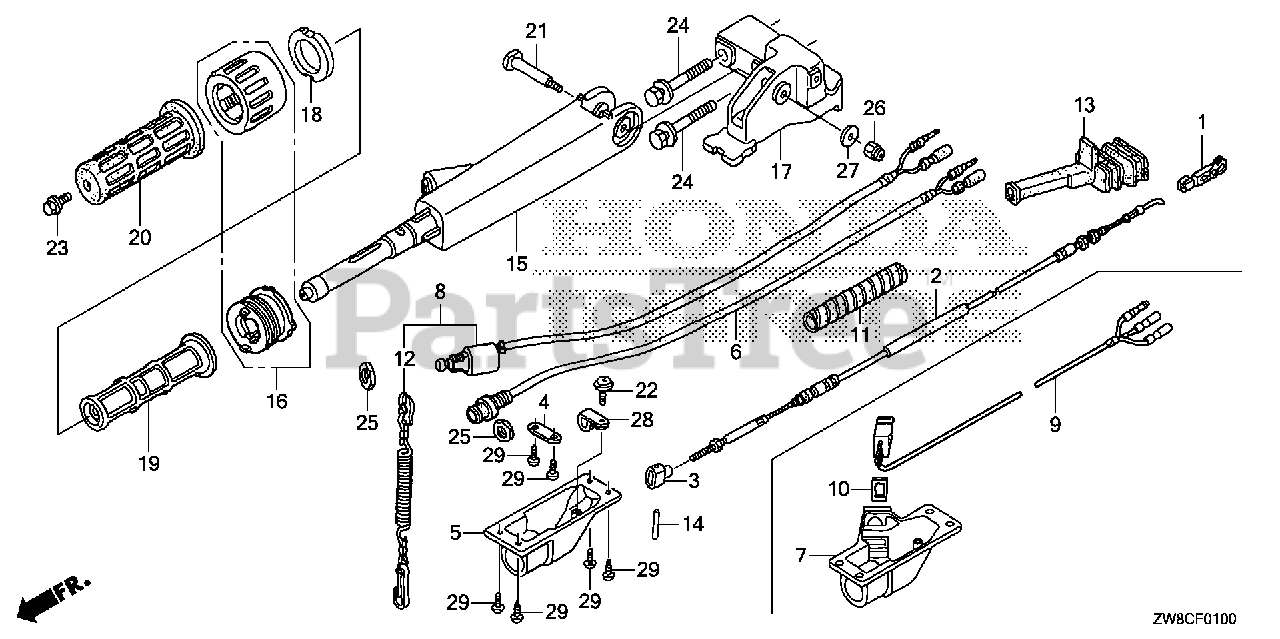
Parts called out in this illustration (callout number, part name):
1	LINKAGE, PIVOT
2	CABLE, THROTTLE
3	PIVOT, THROTTLE CABLE
4	PLATE, SHIFT
8	SWITCH ASSY., EMERGENCY STOP
11	TUBE, SPIRAL B
12	WIRE, EMERGENCY
13	GROMMET, OIL CASE (A)
14	PIN, THROTTLE CABLE
15	HANDLEBAR *NH246* (LOOSY GRAY)
16	GRIP ASSY., THROTTLE FRICTION
16	GRIP, THROTTLE FRICTION (FOR U.S.A.)(COO)
17	BRACKET, HANDLEBAR *NH246* (LOOSY GRAY)
18	PAD, THROTTLE FRICTION
19	PIPE, GRIP
20	RUBBER, GRIP
21	SCREW, HANDLE PIVOT
23	BOLT, FLANGE (6X12)
24	BOLT-WASHER (10X55)
25	NUT, HEX. (16MM)
26	NUT, SELF-LOCK (8MM)
27	WASHER (8MM)
29	SCREW, TAPPING (4X12)
